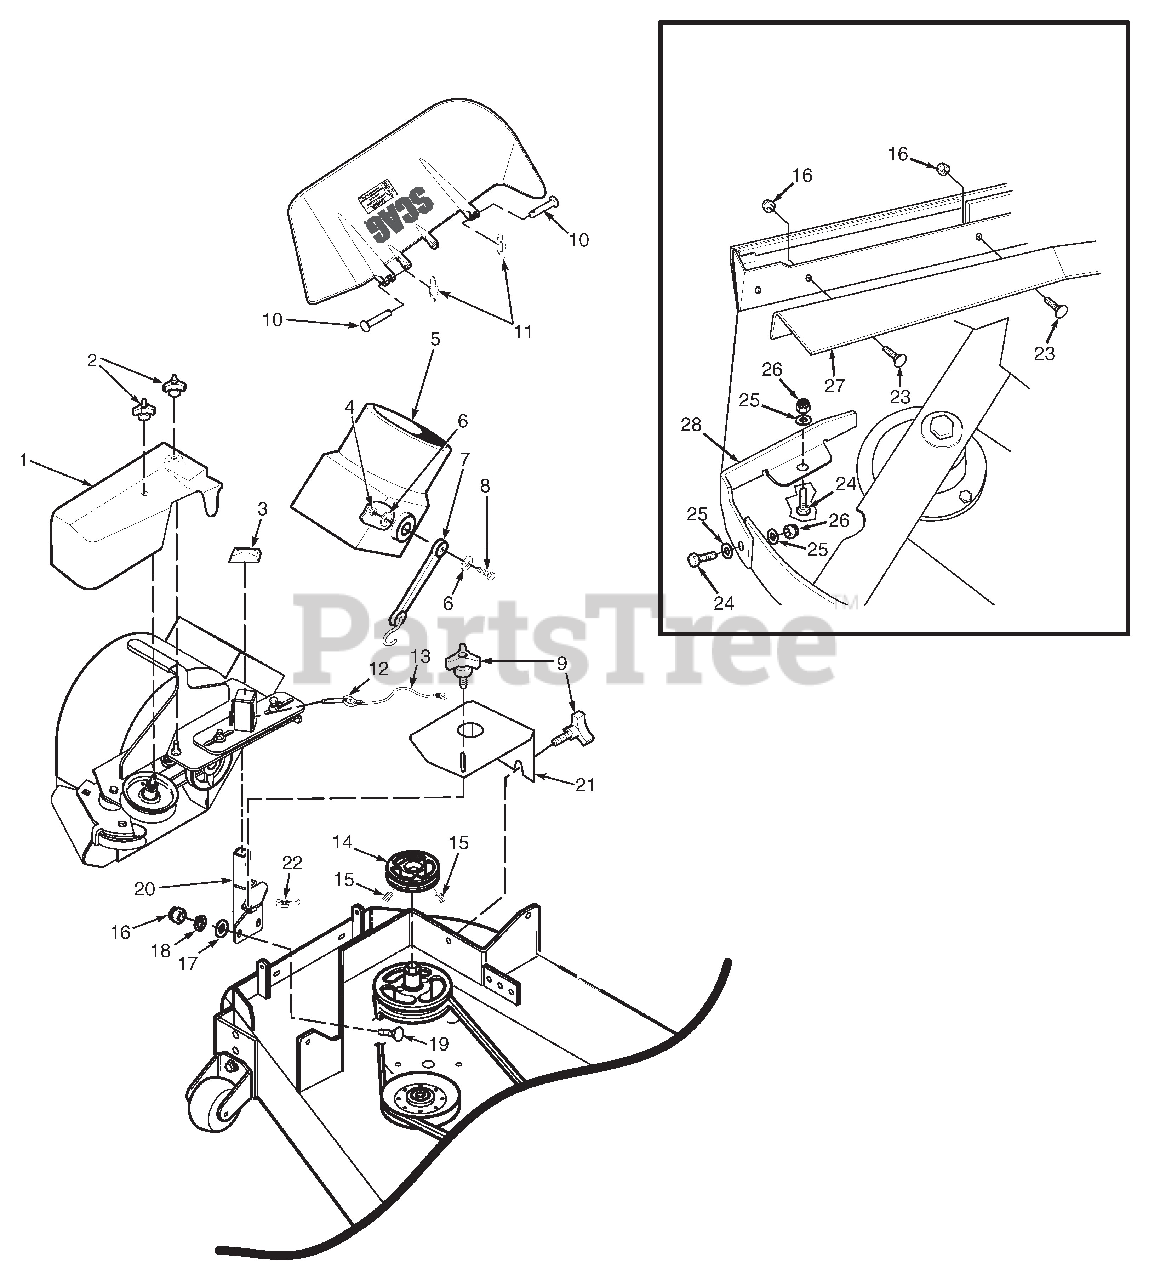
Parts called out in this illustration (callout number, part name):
1	Belt Cover, GC-STT - 52"
2	Wingnut, Plastic 3/8" Small
3	Cap, Square Vinyl
4	Nut, Elastic Stop 1/4-20
5	Adapter, Blower GC-STT,
6	Flatwasher, 1/4-.312 x .750 x .065
7	Rubber Strap 7-3/4"
8	Bolt, Hex Head 1/4-20 x 1-1/4"
9	Knob W/Stud, 3/8-16 x 1-1/4"
10	Clevis Pin, 5/16 x 1-1/2"
11	Pin, Rue Cotter 5/16 Dia.
12	Pin, Ring 1/2 x 2-1/4"
13	Lanyard
14	Pulley, 4-1/2" for 52" Deck
15	Setscrew, 5/16-18 x 3/8"
16	Nut, Elastic Stop 3/8-16
17	Lockwasher, 3/8"
18	Flatwasher, 3/8-.391 x .938 x .105
19	Bolt, Carr. 3/8-16 x 1-1/4"
20	Mounting Post Weldment, Blower - 52"
21	Belt Cover, GC-STT-52V
23	Bolt, Carriage 3/8-16 x 1"
24	Bolt, Hex Head 5/16-18 x 1"
25	Flatwasher, 5/16-.375 x .875 x .083
26	Nut, Elastic Stop 5/16-18
27	Baffle, Front 52" Deck
28	Baffle, Turbo 52" Deck
